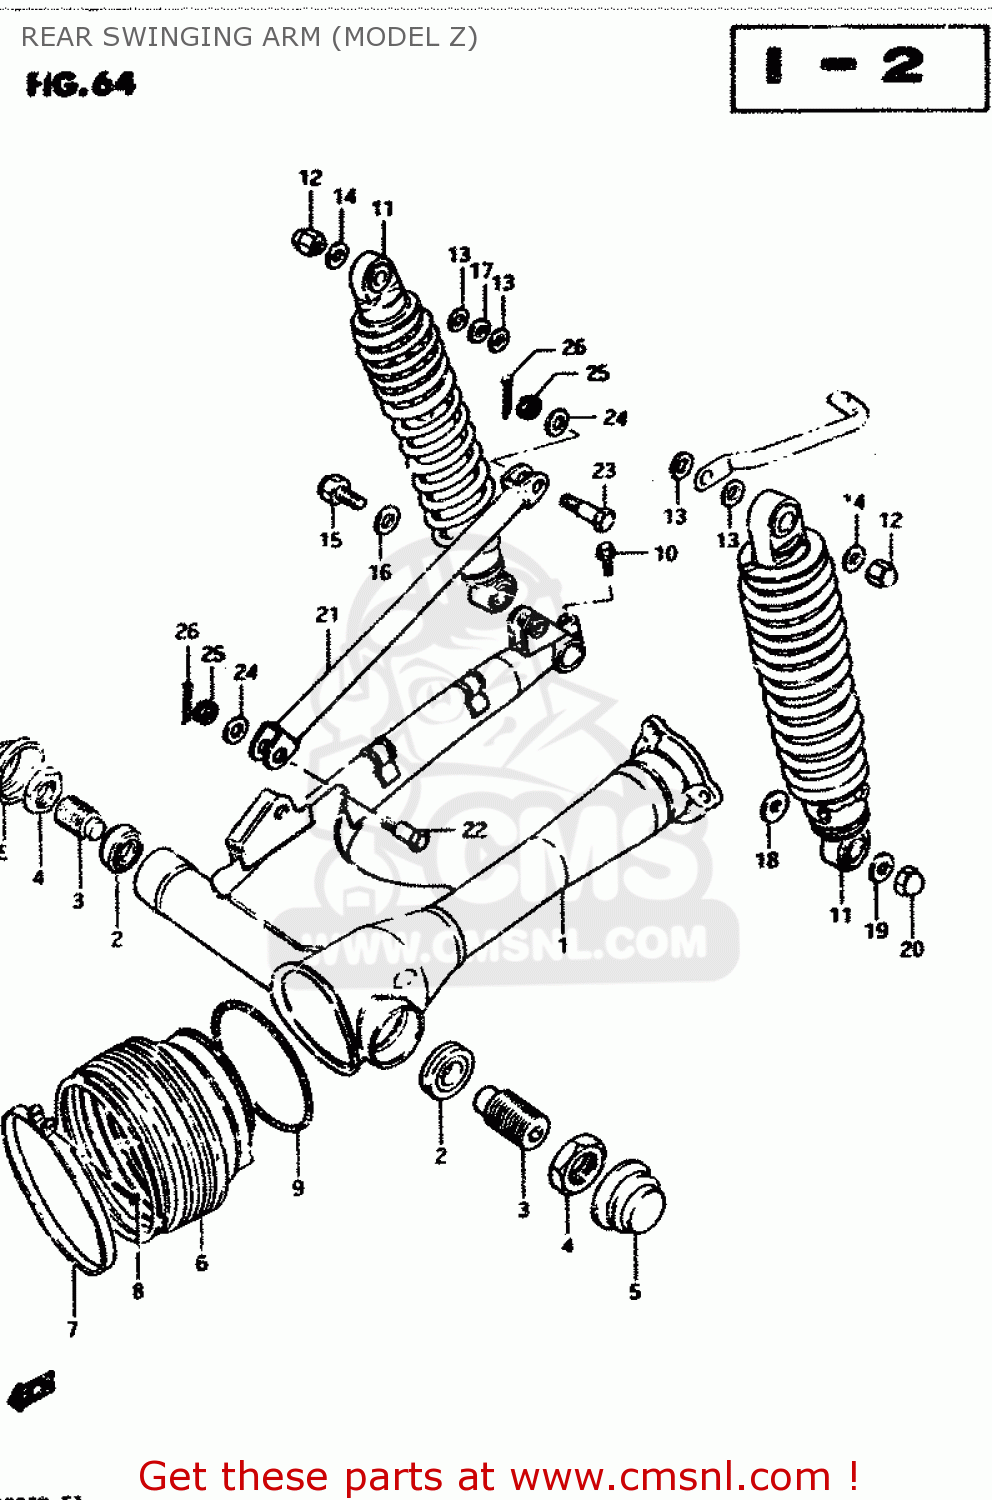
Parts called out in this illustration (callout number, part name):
1	SWING ARM SET,REAR (B
2	BEARING(17X40X13.25)
3	BOLT,REAR SWING ARM PIVOT
4	NUT
5	CAP,REAR SWING ARM PIVOT
6	BOOT,PROPELLER SHAFT
7	CLAMP
8	SCREW 4X25
9	SPRING,PROPELLER SHAFT
10	BOLT
11	SHOCK ABSORBER, REAR
12	NUT
13	WASHER
14	WASHER
15	BOLT 12X33
16	WASHER (12.5X24X1.6)
17	WASHER (12.5X24X3.2)
18	WASHER
19	WASHER
20	NUT, LOWER LH
21	TORQUE LINK,REAR
22	BOLT
23	BOLT(10X39)
24	WASHER
25	NUT
26	PIN 20X20
